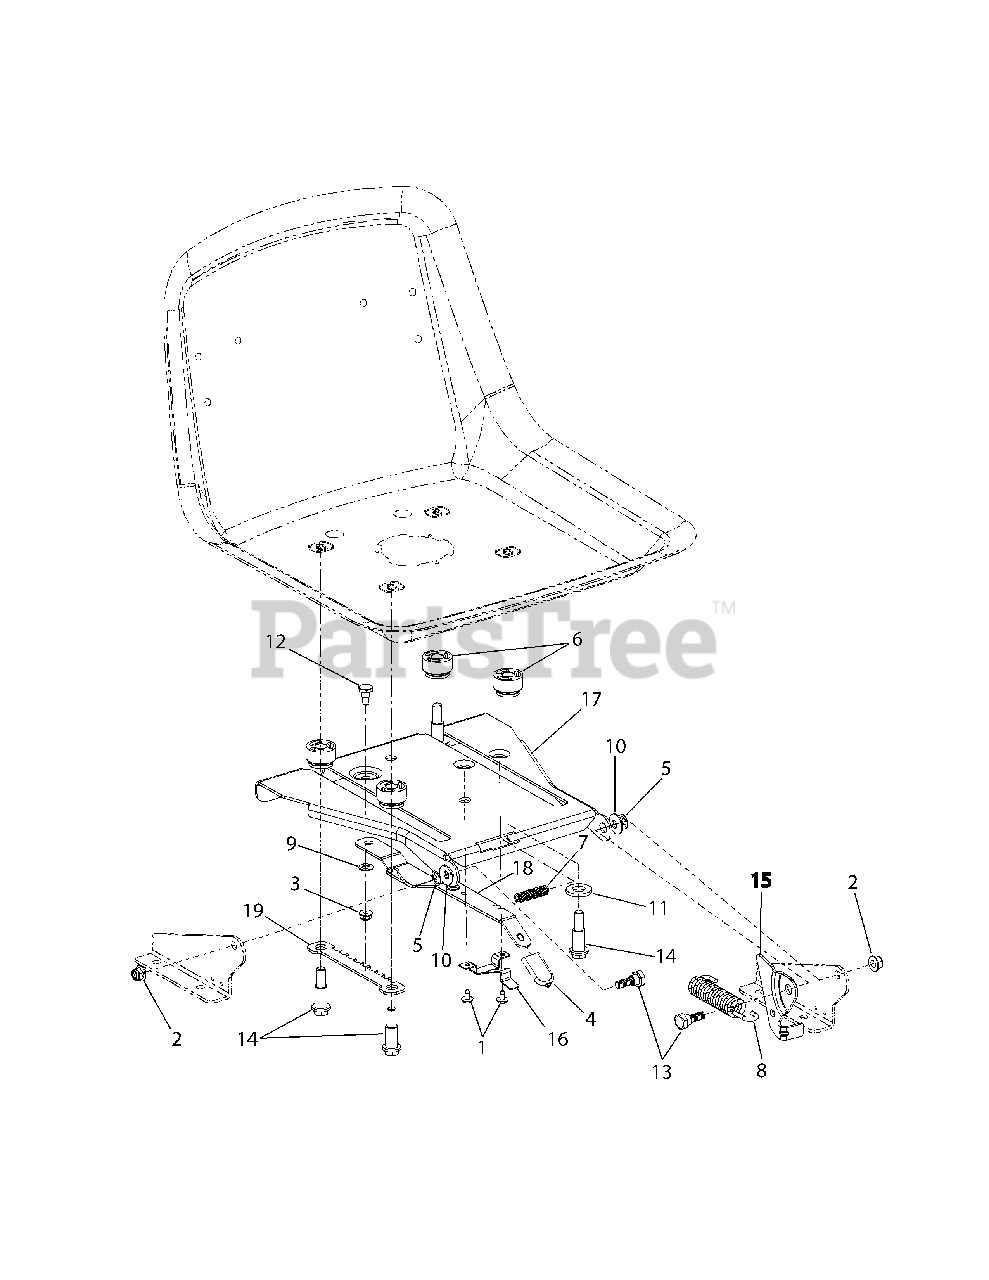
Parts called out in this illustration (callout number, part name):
1	Screw, Hx. Wash. Hd. Tapp #10-16 x .375
2	Nut, Hx Insert Flange Lck, 5/16-18 GrF
3	Nut, Hx Insert Flnge Lck, 1/4-20 GrF
4	Grip, Seat Adjustment
5	Nut, Speed, .3125
6	Spacer, Seat Adjustment
7	Spring, Compression, .41 x 1.5
8	Spring, Extension, .84 Dia. x 4.6
9	Washer, Flat, .344 x .62 x .033
10	Washer, Belleville, .34 x .872 x .06
11	Washer, Flat, .531 x 1.062 x .134 HT
12	Screw, Shoulder, .34 x .285:1/4-20
13	Screw, Shoulder, .437 x .268:5/16-18
14	Screw, Shoulder, .5 x .925:3/8-16
15	Bracket, Seat Lift
16	Stop, Seat Adjustment
19	Index Bracket, Seat Adjustment
